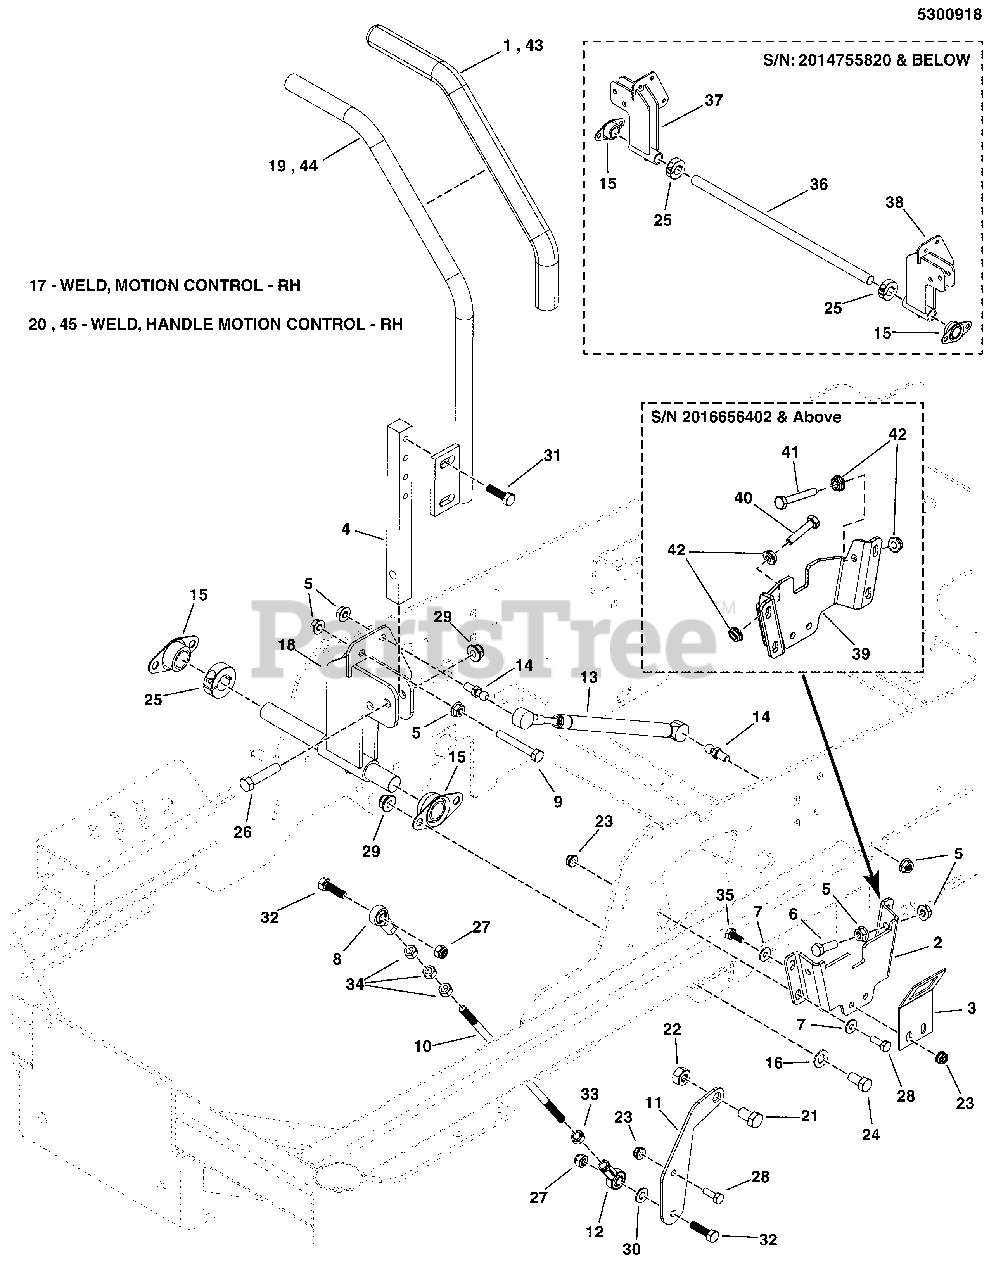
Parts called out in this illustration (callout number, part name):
1	GRIP, FOAM, 3/4" ID, 16"" LONG
2	NEUTRAL LOCK, SNAPPER PRO 36-44 - BLK
3	SWITCH PLATE, MOTION CONTROLS - BLK
4	MOUNT, CONTROL ARM - BLK
5	NUT, 5/16-18 HEX SERRATED FLANGE (SMALL)
6	BOLT, 5/16-18 X 1-1/8 GD5 CZ
7	WASHER, 1/4 SAE
8	BALL JOINT 5/16-24 RH FEMALE STAMPED STL
9	BOLT, 5/16-18 X 2-1/4" GD5 YZ
10	ROD, HYDRO LINKAGE, CZ
11	PLATE, CONTROL LINK, TRANSAXLE - BLK
12	BALL JOINT 5/16-24 LH FEMALE STAMPED STL
13	DAMPENER, CONTROL,#(P6709/P3610)
14	BALL STUD, 5/16 X .50,# PC-477-2)
15	BEARING, BRONZE FLANGE, 3/4"
16	WASHER, 3/8 SAE
18	WELD, MOTION CONTROL, LH - BLK
19	WELD, HANDLE MOTION CONTROL, LH - BLK
20	WELD, HANDLE MOTION CONTROL, RH - BLK
21	BOLT, 7/16-14 X 3/4, GD 5 YZ
22	NUT, 7/16-14 HEX TOP LOCK
23	NUT, 1/4-20 Hex Nylock Flange
24	BOLT, 3/8-16 X 3/4" GD5 CZ
25	COLLAR, 3/4" Split
26	BOLT, 3/8-16 X 1-3/4" GD5 CZ
27	NUT, Hex, Nylon Locking, 5/16-18
28	BOLT, 1/4"-20 X 3/4" GD5 YZ
29	NUT, 3/8 - 16 HEX NYLOCK FLANGE
30	WASHER, 5/16" SAE
31	SCREW-HEX WSHR HD TAPTT5/16-18X0.750BLK
32	BOLT, 5/16-18 X 1-1/8 GD5 CZ
33	NUT, 5/16-24 HEX, LH
34	NUT, Hex, 5/16-24
35	HHCS, 1/4-20 X 0.625, GR5, ZINC/CLEAR
36	SHAFT, 3/4 X 19.52
37	WELD, MOTION CONTROL, RH - RED
38	WELD, MOTION CONTROL, LH - RED
39	NEUTRAL LOCK, 50XT - BLK
40	BOLT, 1/4-20 X 1-1/4 GD5 TFL
41	HEX BOLT, 1/4-20 X 1-3/4 GD 5, TFL
42	NUT, Hex, Serrated Flange, 1/4-20
43	GRIP, FOAM, 1" ID, 16" LONG
44	WELD,HANDLE MOTION CNTRL,17.0,1.0,LH,BLK
45	WELD, HANDLE MOTION CNTRL,17.0,1.0,RH,BLK
